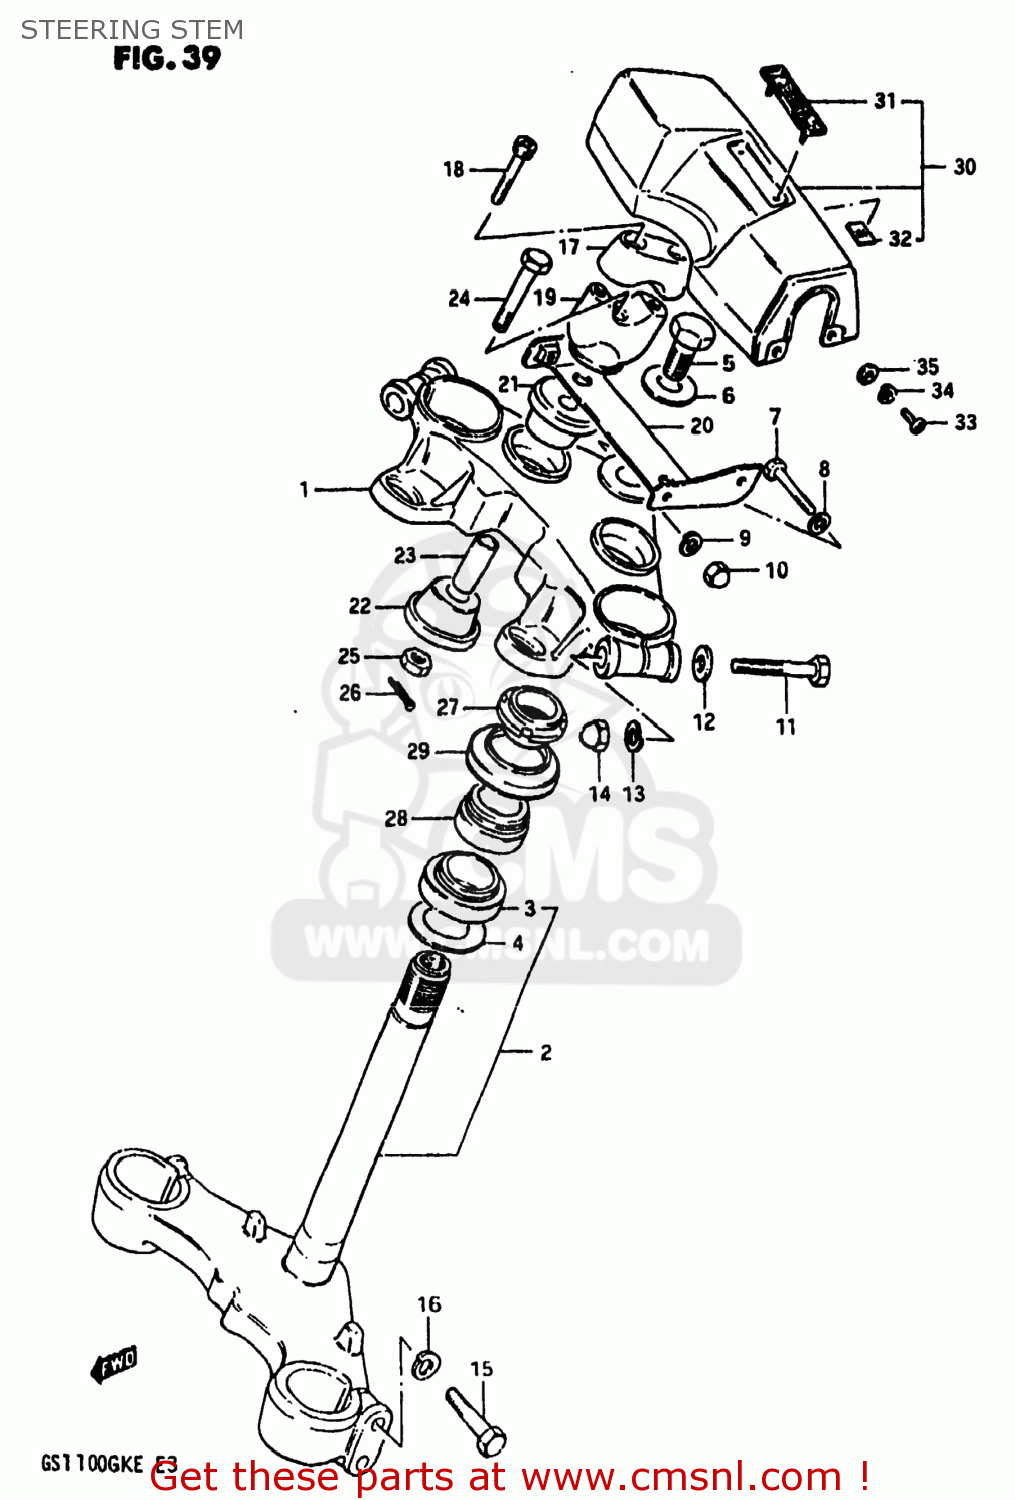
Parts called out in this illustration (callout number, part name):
1	HEAD,STEERING STEM
2	STEM,STEERING
3	BEARING
4	WASHER,THRUST
5	NUT,STEM HEAD
6	WASHER,STEERING STEM
7	BOLT 8X50
8	WASHER
9	LOCK WASHER
10	NUT,M8X1.25X12
11	BOLT 10X55
12	WASHER
13	LOCK WASHER
14	NUT 10MM
15	BOLT 8X40
16	WASHER,LOCK,8.
17	HOLDER,HANDLEBAR
18	BOLT
19	HOLDER,HANDLEBAR
20	BRACKET,STEERING HEAD
21	CUSHION
22	CUSHION HOLDER
23	SPACER(10.2X14X46)
24	BOLT,HANDLE HOLDER
25	NUT
26	COTTER PIN
27	NUT,STEERING STEM
28	TAPER,ROLLER BEARING
29	DUST SEAL,STEERING UPR
30	PAD,HANDLE
31	EMBLEM,HANDLE COVER PAD
32	NUT
33	SCREW
34	WASHER,LOCK
35	WASHER
